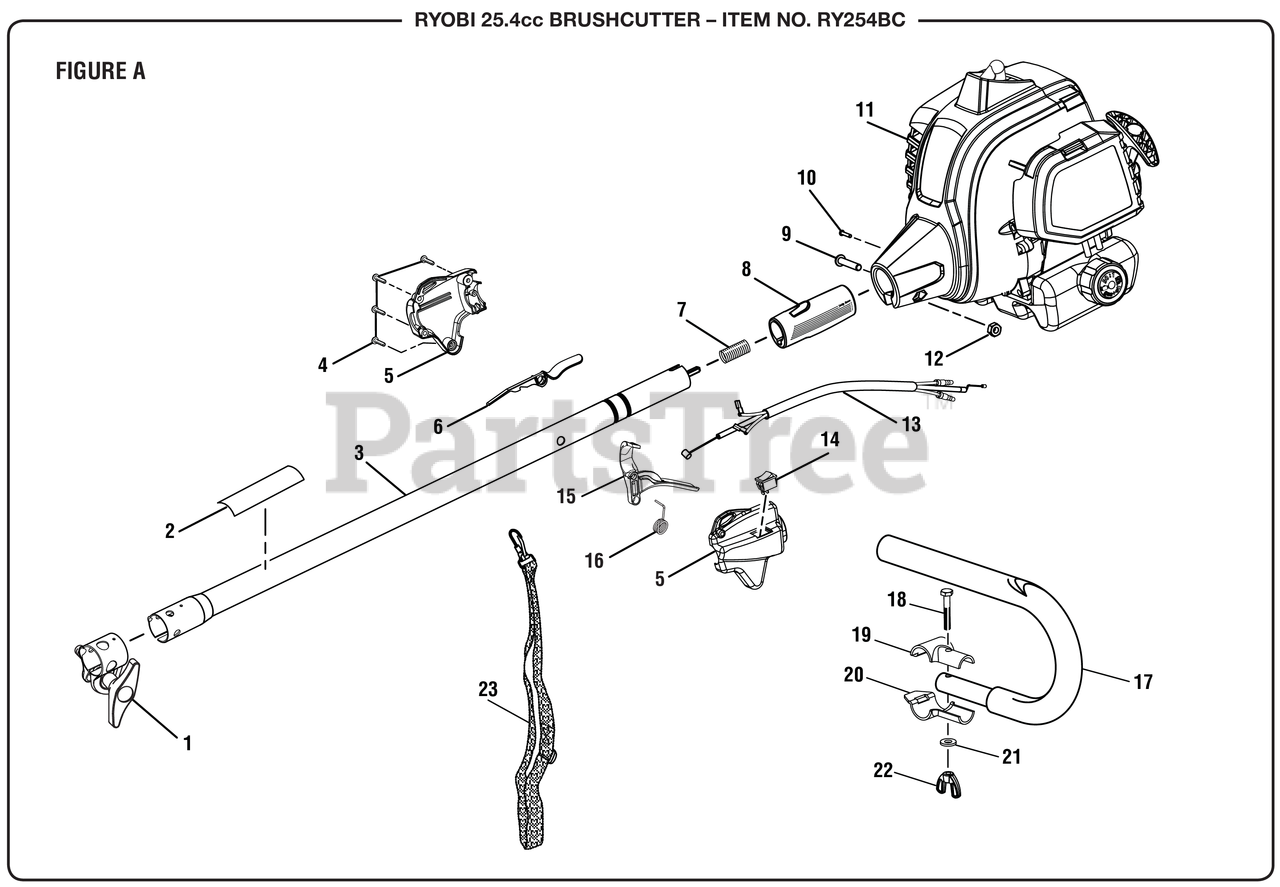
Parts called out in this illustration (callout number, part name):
1	Boom Clamp Assembly
2	Warning Icon Label
3	Upper Boom Assembly
4	Screw (M4 x 20 mm, T20 Torx Pan Hd. S.T.)
5	Control Handle Assembly (Inc. Key No. 6)
6	Trigger Lock
7	COMPRESSION SPRING
8	Rear Handle Grip
9	Screw (M6 x 30 mm, T27 Torx Button Hd.)
10	Screw (M4 x 8 mm, T25 Torx Pan Hd. T.F.)
11	Powerhead Assembly w/Labels
12	Hex Nut (M6.3 x 1)
13	Throttle Cable and Wire Assembly
14	Stop Switch (Momentary Contact)
16	Torsion Spring (Throttle Trigger)
17	"J" Handle and Grip
18	Bolt (1/4-20 x 1-1/2 in., Hex Hd.)
19	Top "J" Handle Clamp
20	Bottom "J" Handle Clamp
21	Washer (ID7.25 x OD16 x 1.5t)
22	Wing Nut (1/4-20, Plastic)
23	Shoulder Harness Assembly
